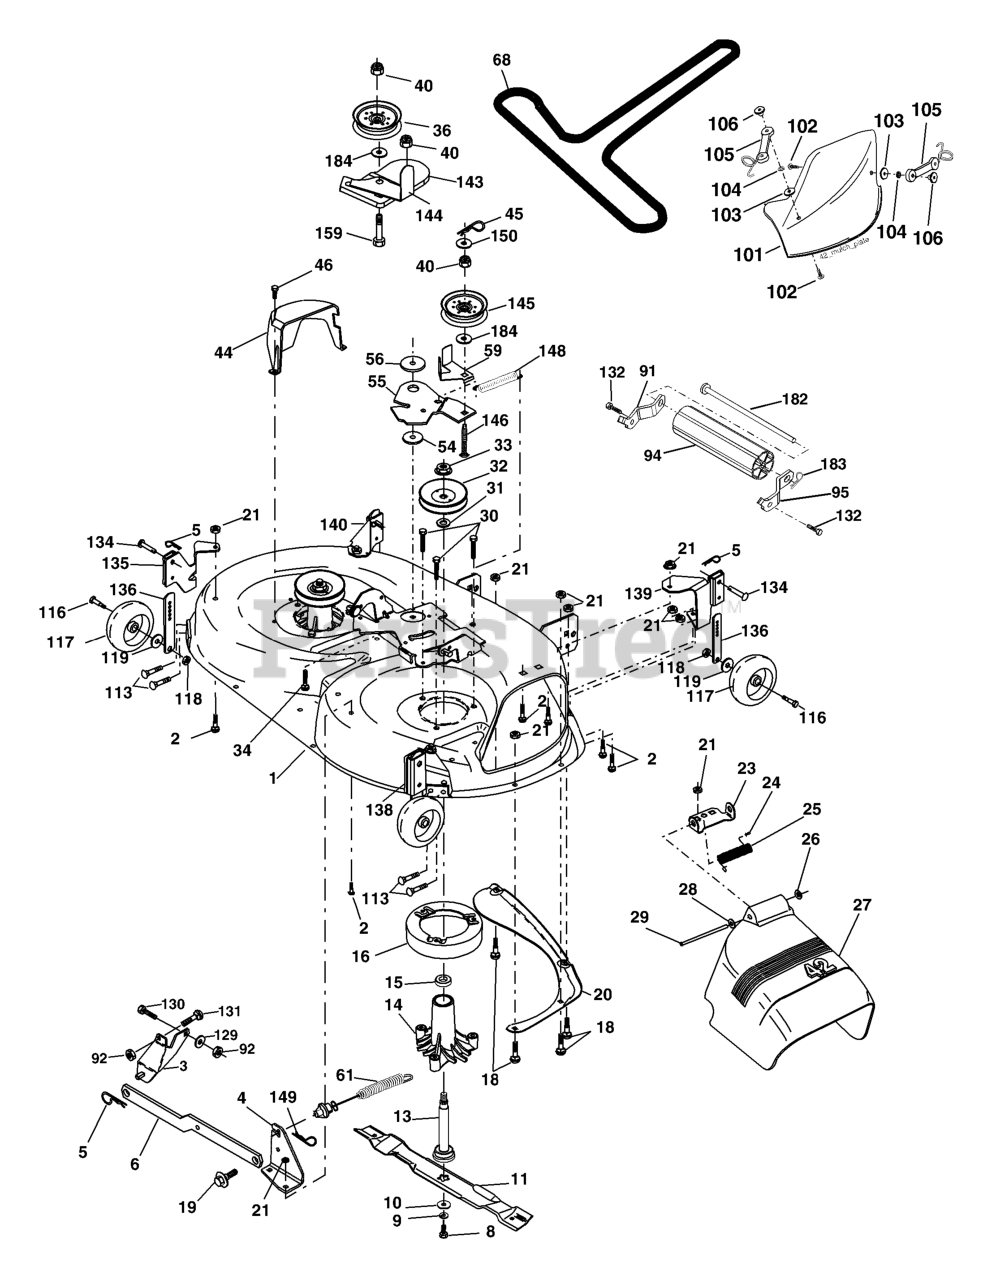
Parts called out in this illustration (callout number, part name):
1	MOWER DECK SHELL 42"
2	RP BOLT 5/16-18 X3/4 ZN/YEL GR
3	BRKT ASM SWAY BAR
4	BRACKET SWAY BAR 42" DECK
5	RETAINER-SPRNG RB
6	BAR SWAY DECK
8	BLADE BOLT
9	LOCKWASHER
10	WASHER.BLADE
11	BLADE.42".MULCH
11	BLADE.42"MULCH.PREMIUM
11	42" HI-LIFT BLADE
13	SHAFT ASM VENT
14	HOUSING.MANDREL.VENTED (MACHD)
16	STRIPPER.MANDREL.ROUND.BLACK
18	BOLT
19	BOLT SHD 5/16-18
20	BAFFLE.VORTEX
21	LOCKNUT
23	BRKT, DEFL. MOWER
24	CAP-SLEEVE LT
25	SPRING TORSION
26	NUT PUSH M
27	SHIELD DEFLECTOR
28	Washer 11/32 x 5/8 x 16 Ga.
29	ROD.HINGE
30	SCREW, WASHER HEAD
31	WASHER.SPACER.MANDREL
32	PULLEY MANDREL
33	NUT, FLG TOPLOCK 9/16"
34	BOLT.3/8-16X1.50
36	PULLEY.IDLER.FLAT
40	NUT LOCK FLG 3/8-16 UNC
44	GUARD MANDREL LH BLACK
45	RETAINER M
46	SCREW.1/4-20X5/8
55	ARM IDLER 42" MOWER LT/YT
56	SPACER RETAINER
59	GUARD TUV IDLER
61	SPRING EXT ELEC CLUTCH
68	V-BELT PRIMARY 42"
91	BRACKET ASM NOSEROLLER LH
92	NUT
94	NOSE ROLLER
95	BRACKET ASM NOSEROLLER RH
101	COVER MULCH 42"
102	SCREW
104	LOCKWASHER #10
105	LATCH ASSY
106	WELDNUT
113	SCREW 5/16"
116	BOLT M
117	WHEEL.GAUGE.STANDARD
118	LOCKNUT
119	WASHER.5/16.FLAT.STE.STD.
129	WASHER
130	BOLT
131	BOLT D
132	SCREW, 3/8-16X3/4
134	RIVET.PIN.HEAD.YELLOW.
135	BRACKET ASM, WHEEL
136	BAR.ADJUST.WHEEL.ANTI.SCALP.BL
138	BRACKET.ASM.WHL.GA.R.RH.42".GR
139	BRACKET ASM, WHEEL
140	BRACKET ASM, WHEEL
143	BRACKET, ARM IDLER
144	KEEPER BELT 42" CLUTCH
145	PULLEY.IDLER.FLAT.PLATED
146	BOLT CARRIAGE IDLER
148	IDLER RETURN SPRING
149	SPRING.RETAINER.YELLOW.ZINC
150	WASHER LT
159	BOLT
182	ROD ROLLER NOSE STANDARD
183	SPRING RETAINER
184	WASHER
